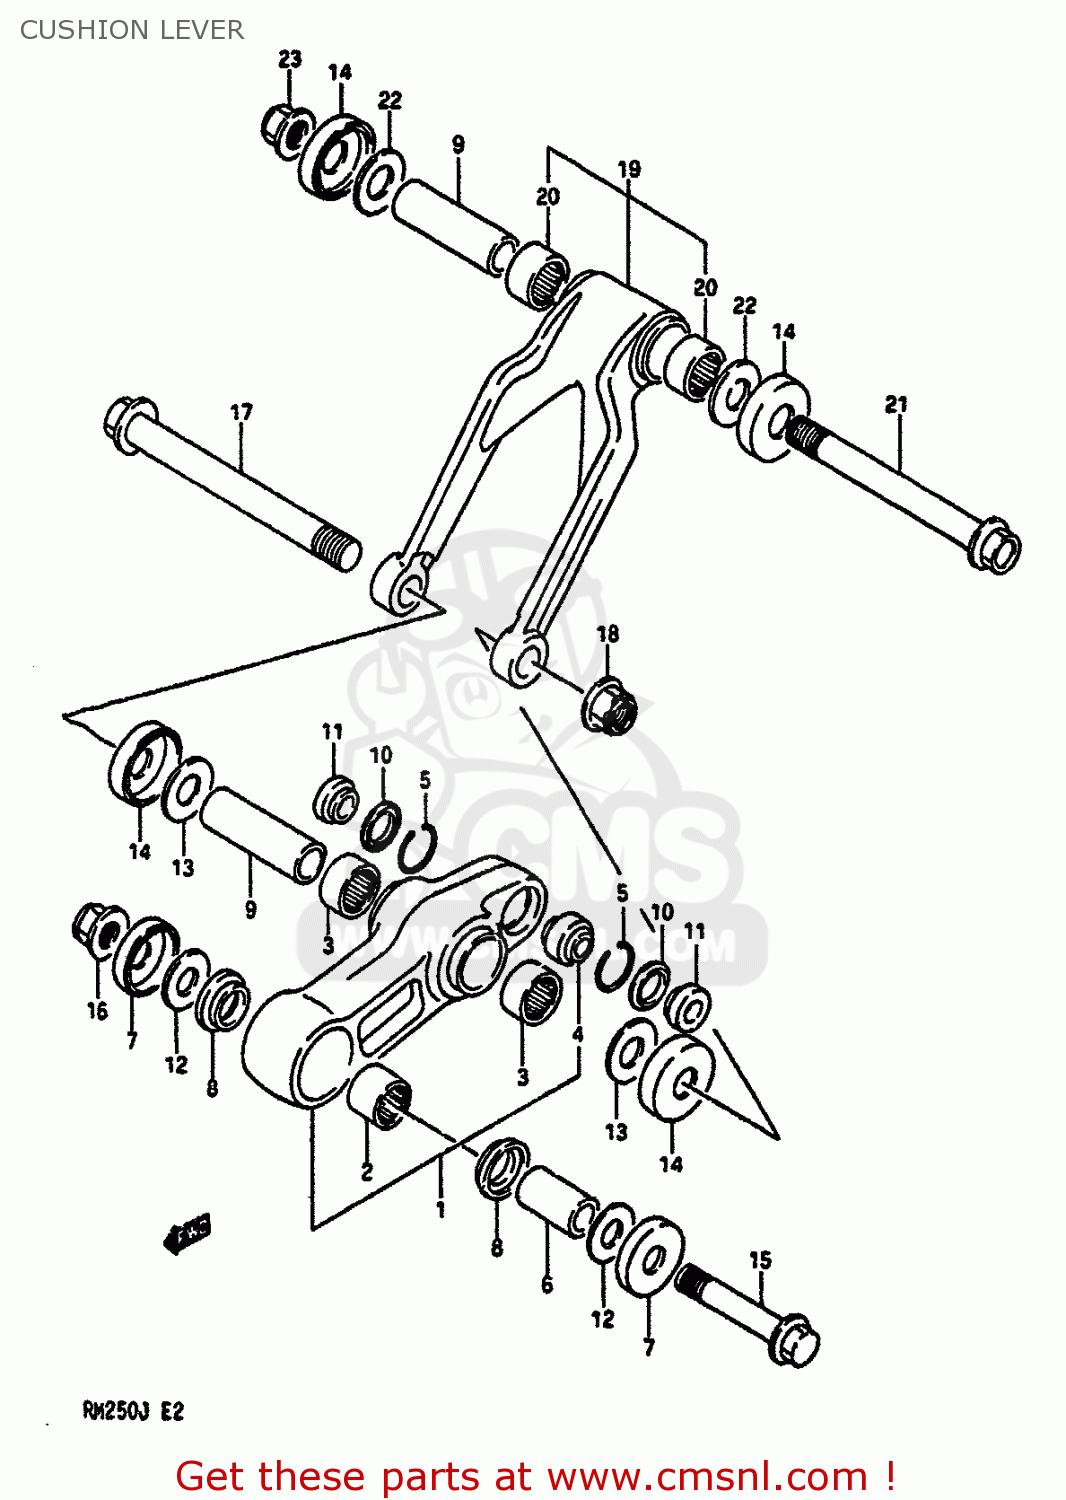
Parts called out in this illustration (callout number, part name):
1	LEVER SET,REAR CUSHION
2	BEARING(20X27X25)
3	BEARING(20X27X20)
4	BEARING,RR CUSHION LEVER
5	RING
6	SPACER,REAR CUSHION LEVER
7	COVER,REAR SWING ARM DUST
8	COLLAR,RR CUSHION LEVER FR
9	SPACER,REAR CUSHION LEVER
10	SEAL,DUST RR SHOCK ABSORBER
11	COLLAR
12	WASHER
13	WASHER
14	DUST SEAL,RR C
15	BOLT,RR CUSHION LEVER FR
16	NUT 12MM
17	SHAFT,RR CUSHION LEVER
18	NUT
19	LEVER SET,REAR CUSHION
20	BEARING(20X27X20)
21	BOLT,REAR CUSHION ROD
22	WASHER
23	NUT
